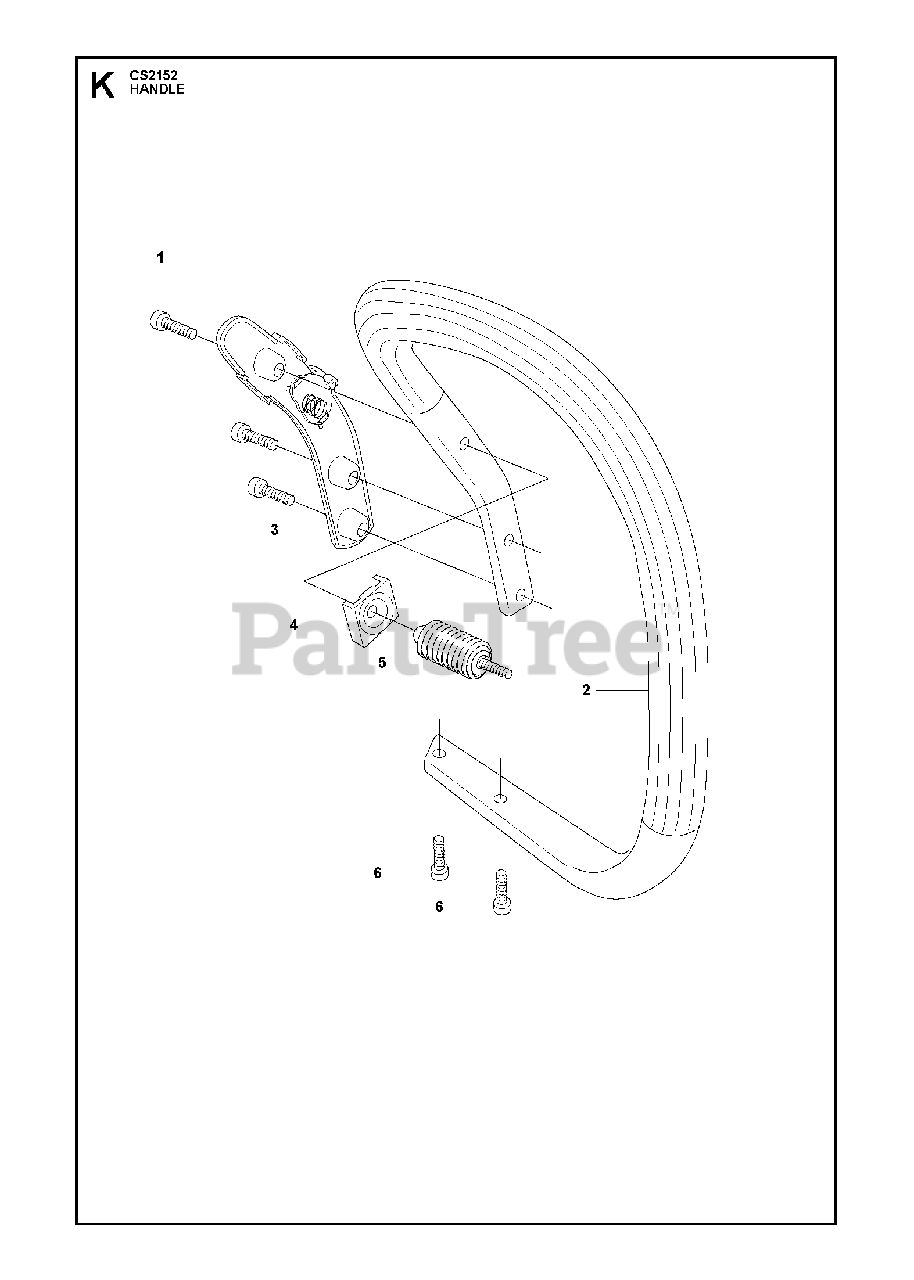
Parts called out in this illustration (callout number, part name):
2	FRONT HANDLE
2	HANDLE
3	SWITCH
5	INSULATOR
6	SCREW IHSCFT
